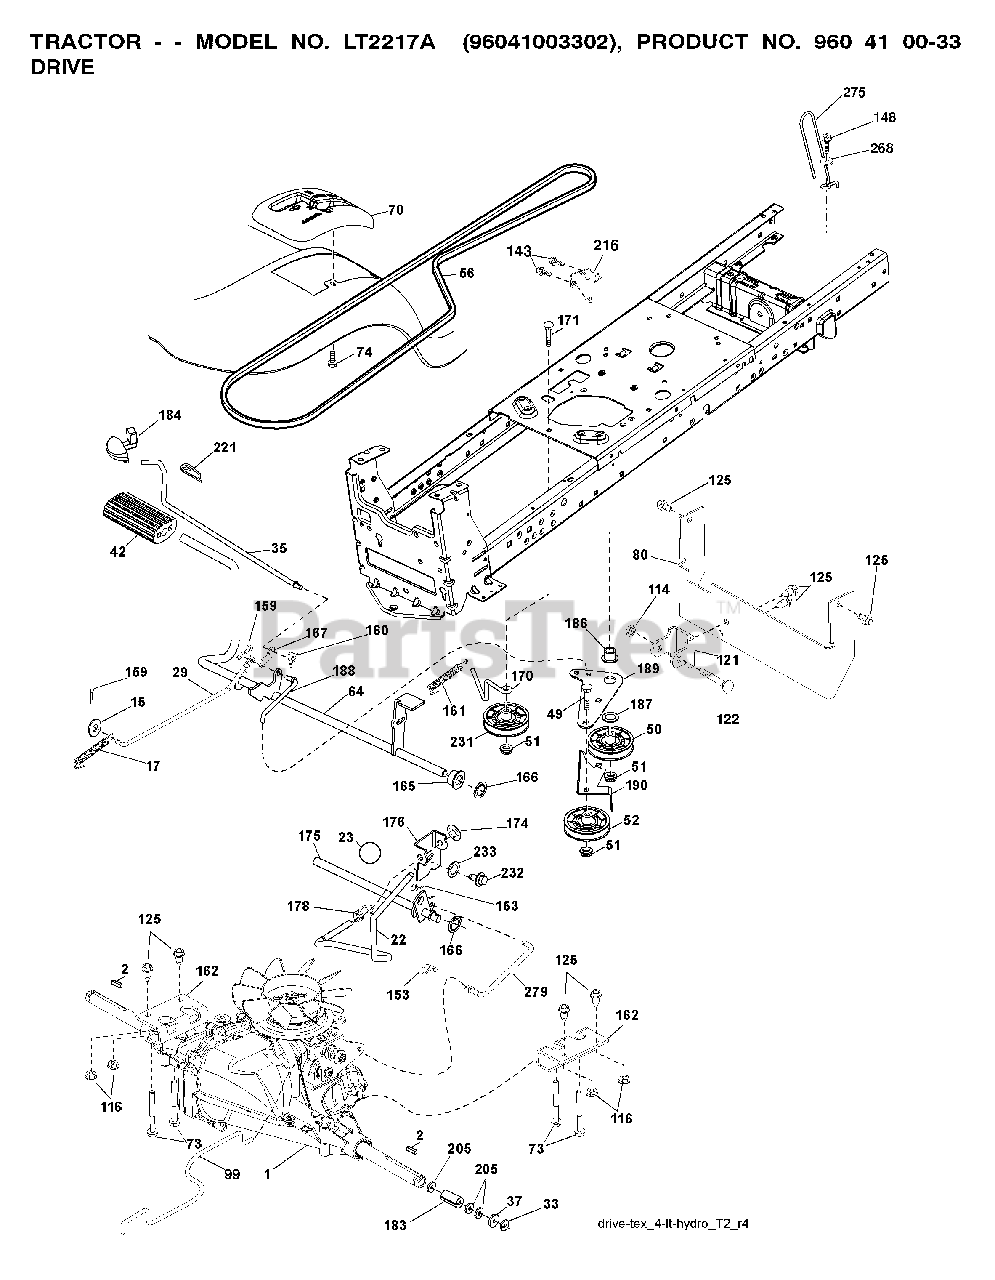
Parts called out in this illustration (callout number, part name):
2	SQUARE KEY
17	SPRING.BRAKE.HG3000/3500
22	ROD.SHIFT.FENDER.TLT.2006
23	KNOB.DUCKHEAD.1/2
29	ROD.BRAKE.T2.TEX
33	E-RING LT
35	ROD.BRAKE.PARKING.LT.T
42	PEDAL COVER T
49	BOLT
50	IDLER.FLAT.910.OFFSET
51	NUT LOCK FLG 3/8-16 UNC
52	IDLER.V-GROOVE.910.OFFSET
64	SHAFT.ASM.PEDAL.BRAKE.
70	CONSOLE.SHIFT.STL.HYD.BLACK
73	BOLT HEX 5/16-18 GR 5
74	SCREW.HI-LO.CONSOLE
80	STRAP.TORQUE.FS.T2
99	ROD.ASM.BYPASS.SPRING.T2.FS
114	NUT.71038.31-18.HEX.NYLOCK
116	NUT LOCK HEX FLANGE 5/16-18
121	BRACKET STRAP TORQUE
122	BOLT.5/16-18X2.5
125	SCREW
148	SCREW, 3/8-16X3/4
153	RETAINER M
159	COTTER PIN
160	RETAINER CLIP
161	SPRING, RETURN LT
162	ADAPTER.TRANSAXLE.T2.TLT.DRWBR
165	BUSHING.SHAFT.BRAKE.HAND
166	NUT.PUSH.625.2006
167	LATCH.BRAKE.SPRING
170	KEEPER.CENTER SPAN.1.688
174	NUT.PUSH.500.2006
175	SHAFT.ASM.SHFT.T2.TLT
176	ARM.CLEVIS.ROD.SHIFT
178	SPRING.SHIFT.GT2006
183	SPACER, AXLE PVST
184	HANDLE.PAKRING.BRAKE.
186	SPACER.RETAINER
187	WASHER 12/32X2X10GA
188	LINK.CLUTCH.GROUND.DRIVE
189	BELLCRANK.GROUND.DRIVE.TEX.
190	KEEPER.BELLCRANK.DRIVE
216	BRACKET.PULLEY.IDLER.W/TEX
221	RETAINER.SPRING.CLIP.H
231	IDLER.V-GROOVE.1.688.OFFSET
232	BOLT FIN HEX 7/16-14 X 1
233	WASHER SERRATED
268	WASHER
279	LINK SHIFT
